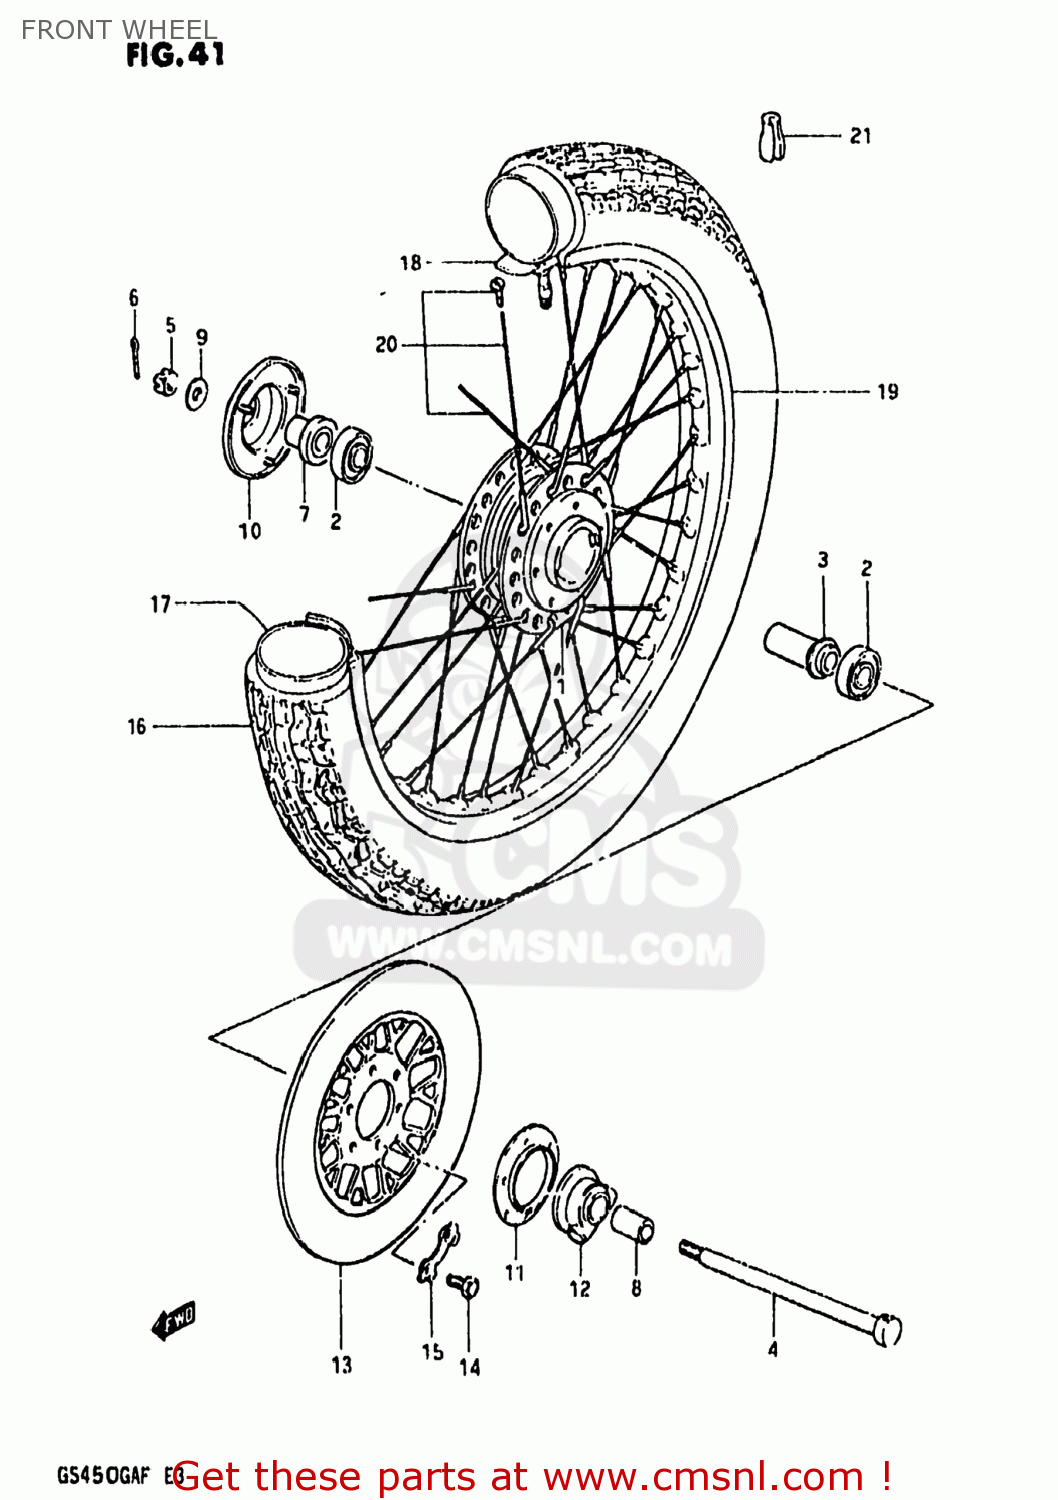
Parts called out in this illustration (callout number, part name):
1	DRUM,FRONT HUB
2	BEARING
3	SPACER,FR HUB BEARING
4	AXLE,FRONT
5	NUT 12MM
6	COTTER PIN
7	SPACER,FR HUB BEARING,R
8	SPACER(15X22X30)
9	WASHER
10	COVER,FR HUB,R
11	DUST SEAL,SPEEDOMETER GEAR BOX
12	BOX ASSY,SPEEDOMETER GEAR
13	DISC,FR BRAKE
14	BOLT(8X25)
15	WASHER
16	TIRE
17	TUBE,INNER
18	PROTECTOR,INNER TUBE
19	RIM,FRONT WHEEL
20	SPOKE ASSY,FR WHEEL
21	BALANCER,WHEEL (B)
